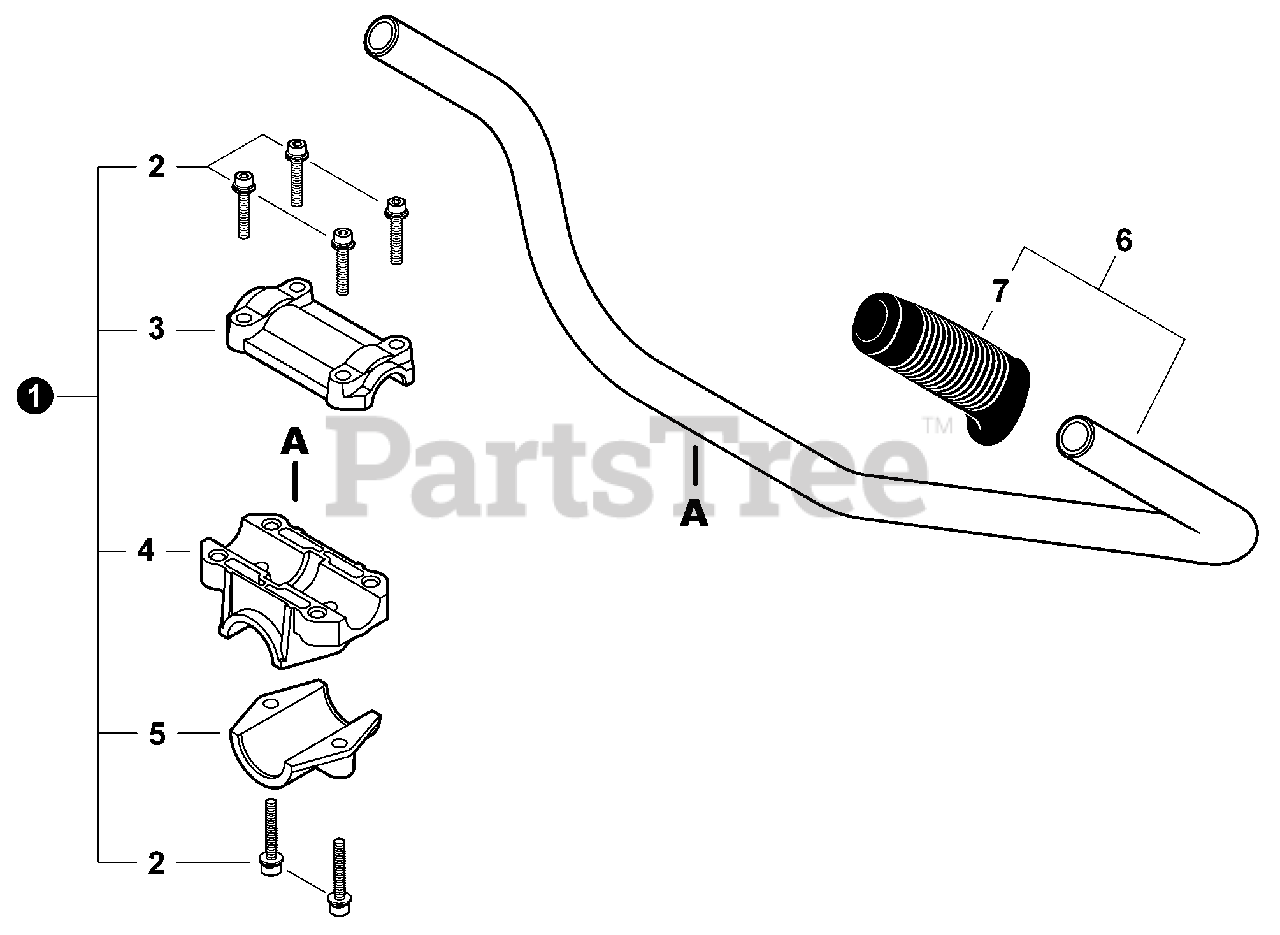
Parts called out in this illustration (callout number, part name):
1	BRACKET KIT, HANDLEBAR
2	BOLT M5×25
3	BRACKET, UPPER
4	BRACKET, LOWER
5	BRACKET, MOUNTING
6	HANDLEBAR ASSY
